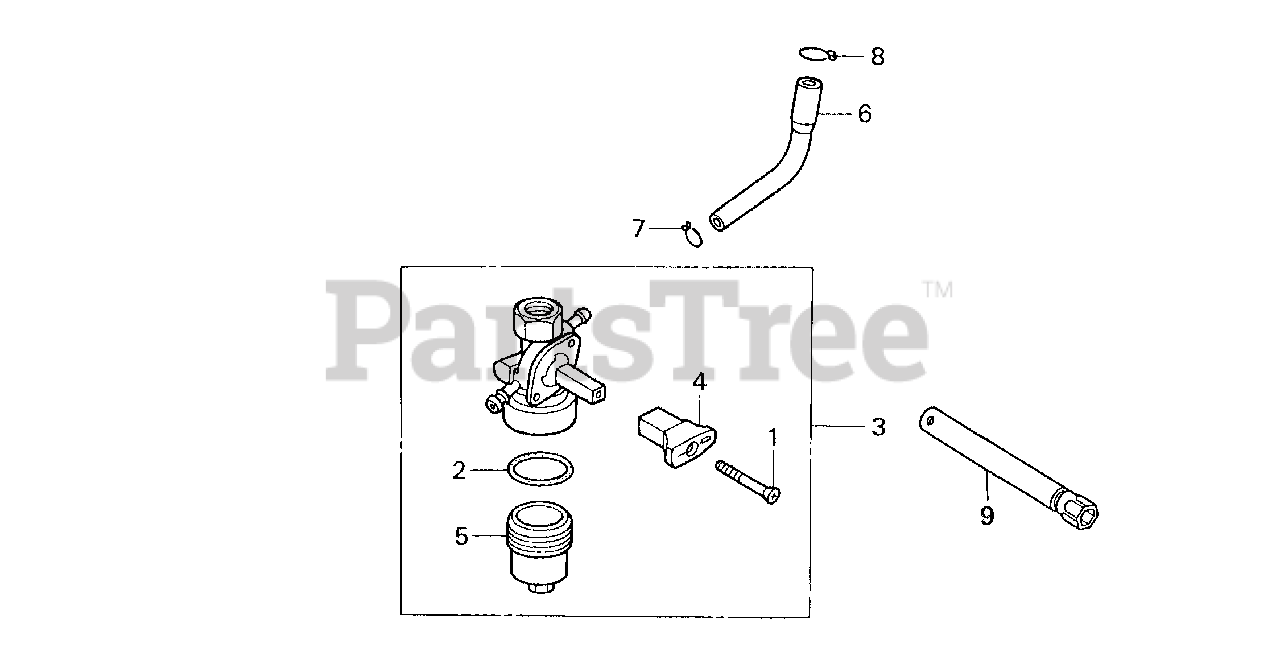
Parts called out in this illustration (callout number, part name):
1	SCREW, OVAL (4X32)
2	GASKET, FUEL STRAINER CUP
3	PETCOCK ASSY.
4	LEVER, PETCOCK
5	CUP, FUEL STRAINER
6	TUBE, FUEL
6	TUBE, FUEL (EXEN)
7	CLIP, TUBE (B8)
8	CLIP, TUBE (10.5MM)
9	WRENCH, SPARK PLUG
